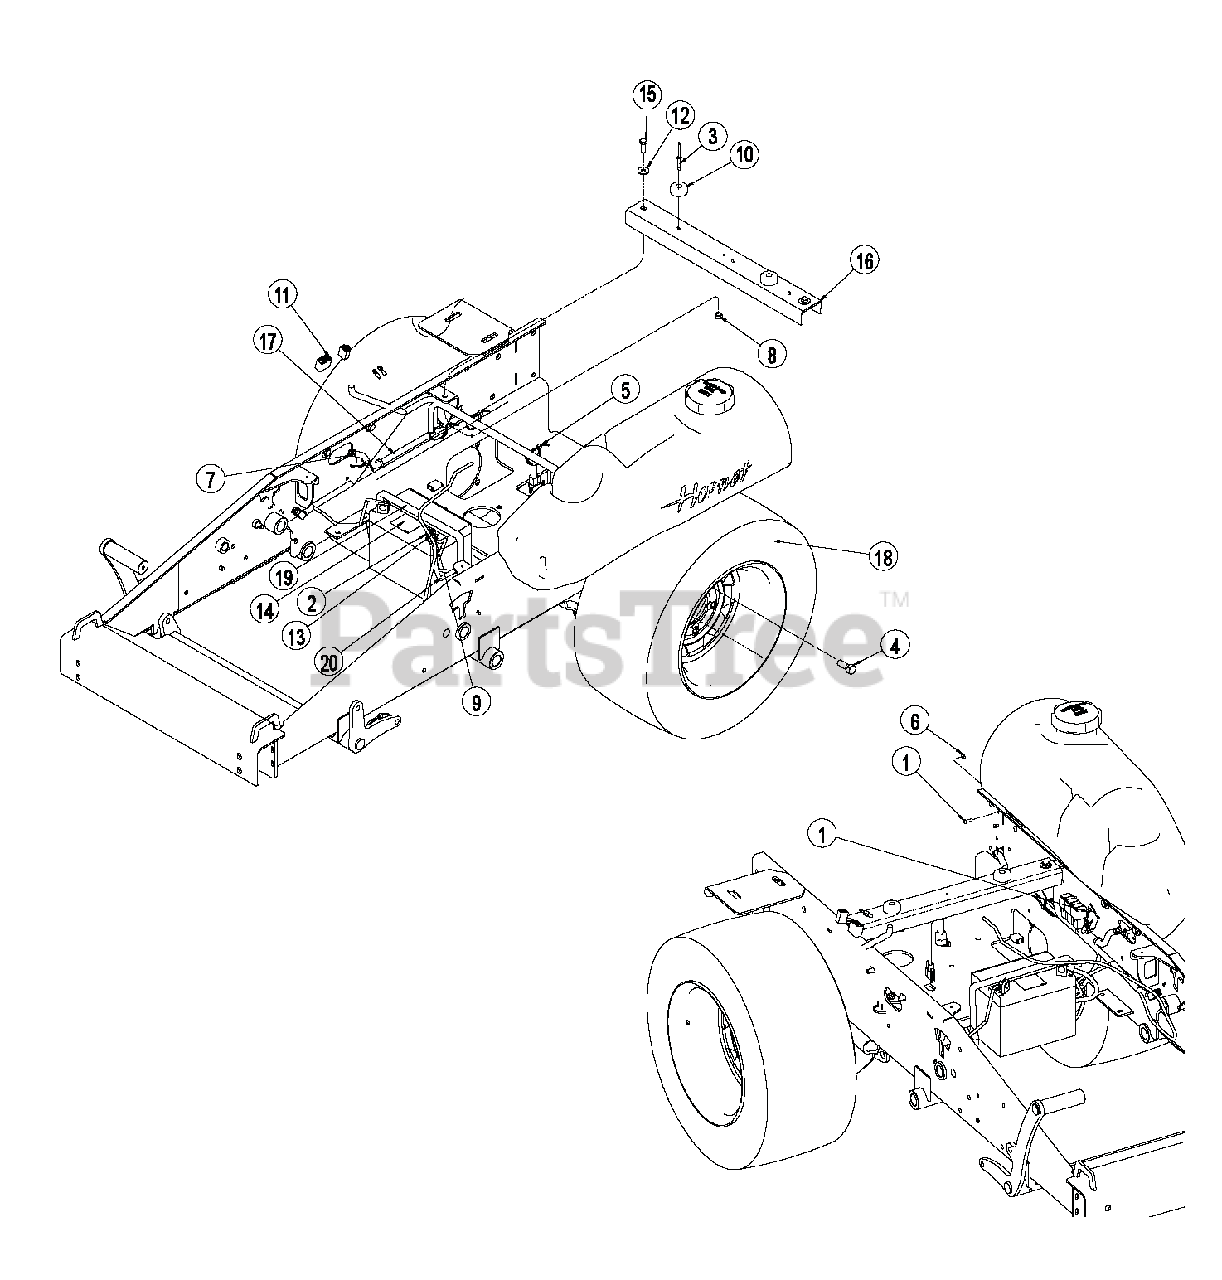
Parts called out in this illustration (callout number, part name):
1	SCREW, 10-24X.625 PAN PHL MACY
2	BOLT, 5/16-18X.750 CRG 5 Y
3	RIVET, 3/16 X .500 POP
4	BOLT, 1/2-20X1.00 LUG Y
5	CABLE TIE, .15 X 8.50
6	NUT, 10-24 KEPS Y
7	CLAMP, HOSE - 1/2" SPRING
8	LOCKNUT, 3/8-16 CROWN Y
9	NUT, 5/16-18 STD HEX GR5 Y
10	BUMPER, RUBBER .625 X 1.50 DIA
11	HARNESS, POWER UNIT WIRE
12	WASHER, .375 REG FLAT Y
13	WASHER, .313 MED SPRG LOCK
14	DECAL, DANGER - BATTERY
15	BOLT, 3/8-16X1.00 HEX 5 Y
16	PLATE, TOP CROSSMEMBER
17	ASSY, FUEL LINE W/CHECKVALVES
18	ASSY, TIRE & RIM - 23X10.50-12
19	BAND 15"
20	CABLE, BATTERY - 35" POSITIVE
